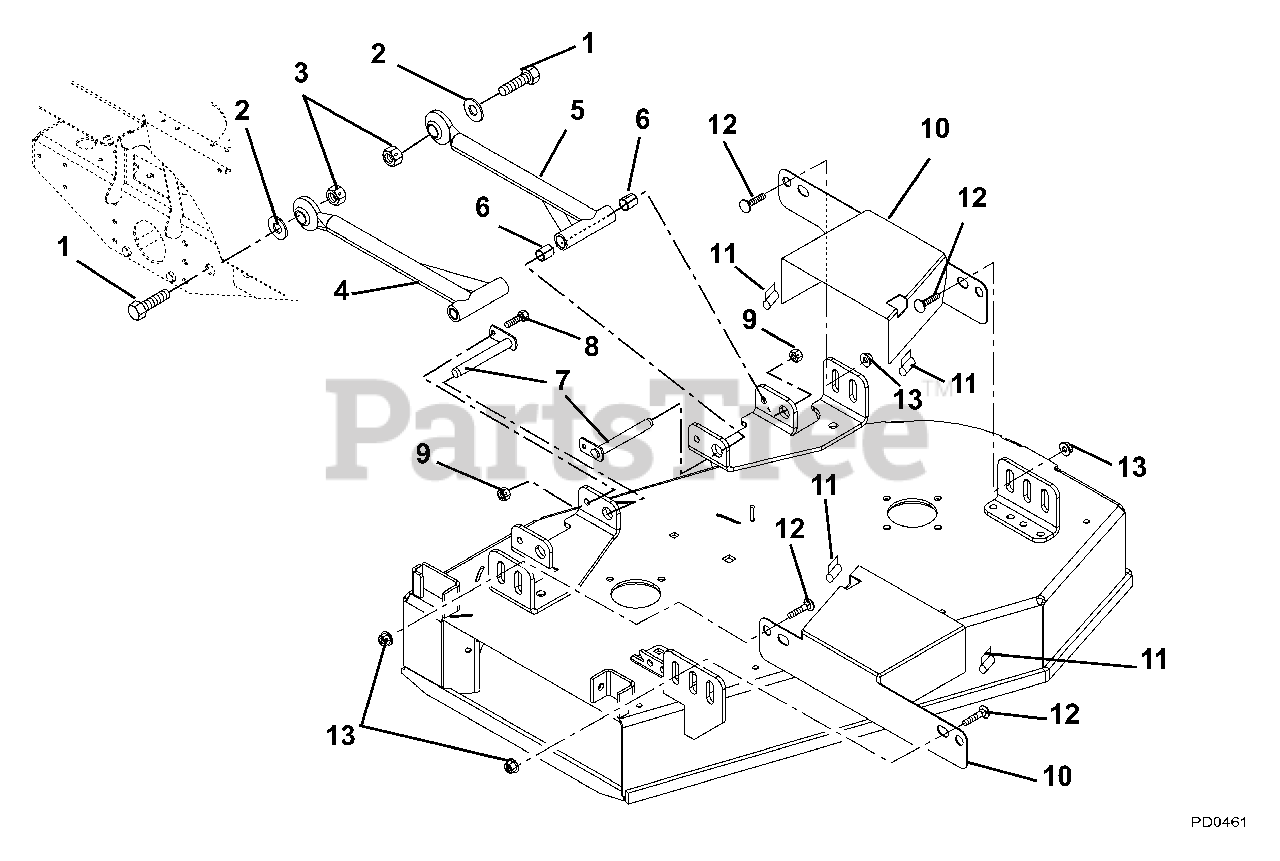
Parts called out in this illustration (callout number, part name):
1	Bolt, Hex .875-9 x 3.00
2	Bushing, Sleeve .875 x 1.25 x .531
3	Nut, Locking Center .875-9
4	Assembly, Mower Mounting
5	Arm, Mower Mounting
6	Bearing, .75 x .875 x 1.00
7	Weldment, Mower Mounting Pin
8	Bolt, Hex .38-16 x 1.00
9	Nut, Nyloc Flange 3/8-16
10	Guard, 34" Belt
11	Seal, Trim-LOK Bulk .06 Bubble
12	Bolt, Round Head Square Neck .50-13 x 1.00 Grade 5
13	Nut, Nyloc Flange .50-13
